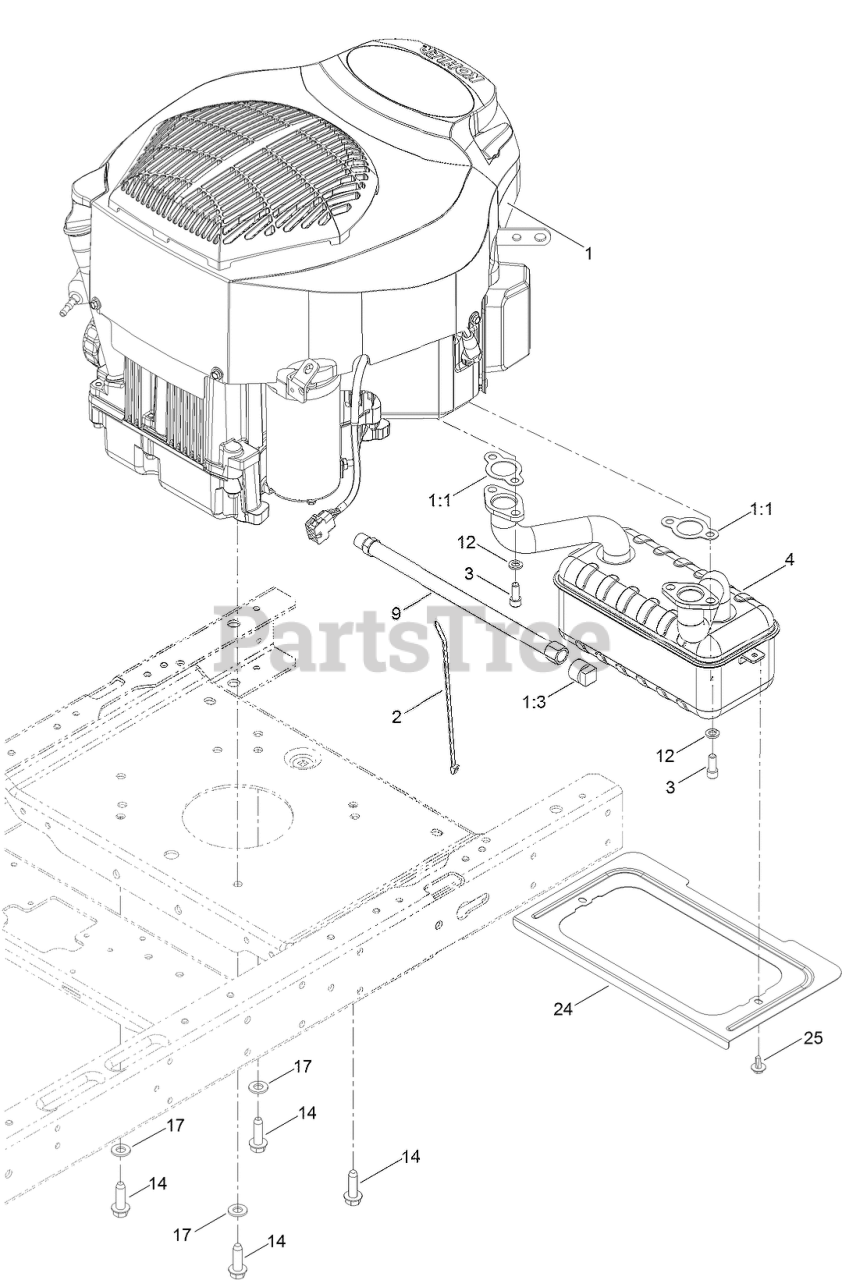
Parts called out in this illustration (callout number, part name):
1	ENGINE-KOHLER 22HP 7000 SERIES AUTOCHOKE
1:1	GASKET-EXHAUST
1:3	PLUG-PIPE, SQH
2	TIE-CABLE
3	SCREW-HSH
4	MUFFLER
9	HOSE-DRAIN, OIL
12	WASHER-LOCK
14	SCREW-TAPTITE
17	WASHER-FLAT
24	SHIELD-HEAT
25	SCREW-HHFTF
